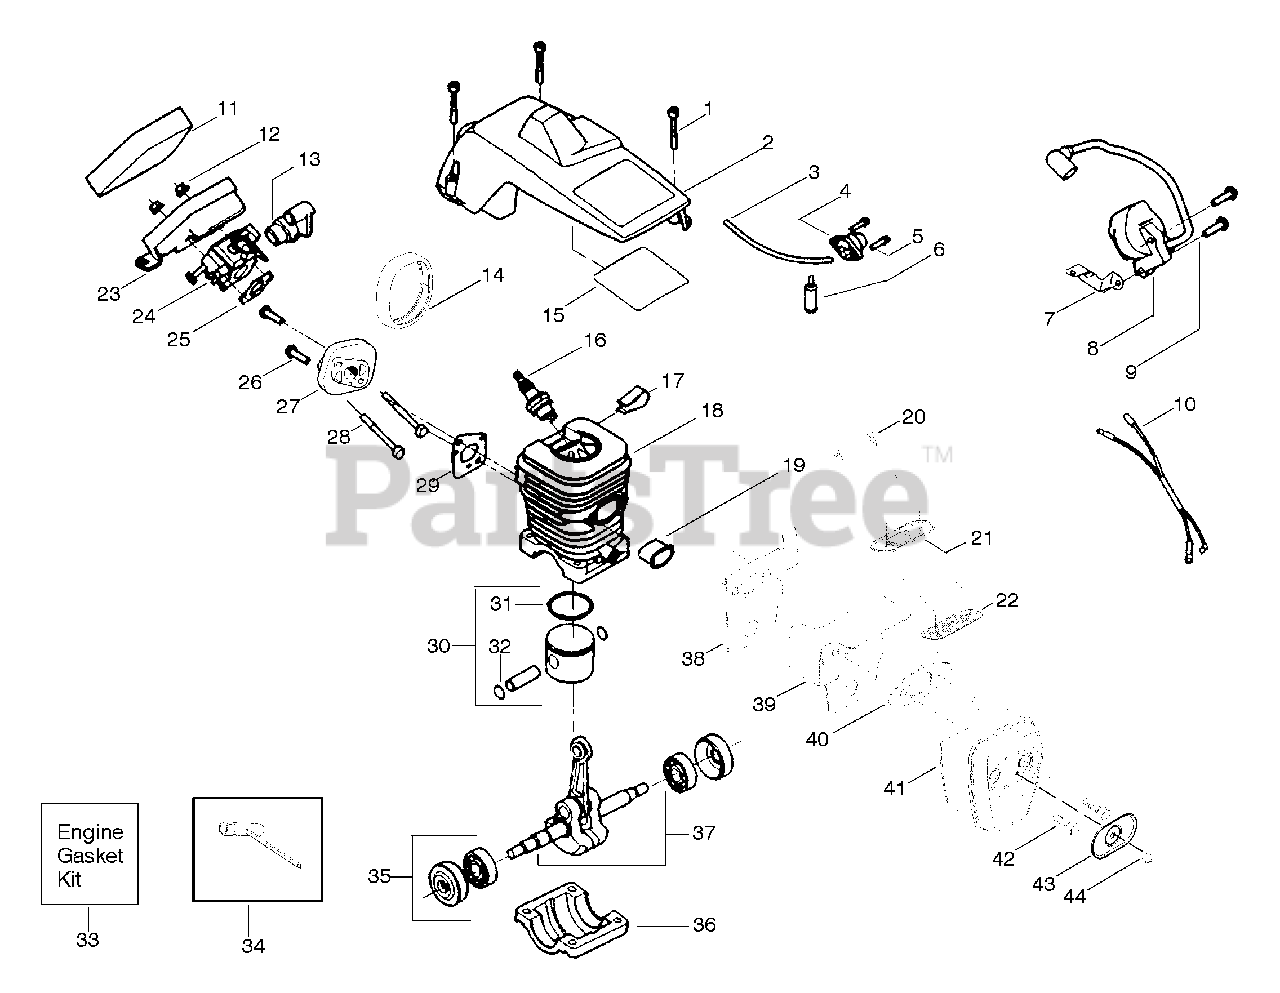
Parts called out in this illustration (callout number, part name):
2	Assy-Cylinder Shield
3	Kit-Fuel Line (Small)
4	Assy-Air Purge
6	Assy-Fuel Pick-up
7	Strap-Ground
8	Ignition Module
10	Assy-Wire Harness
11	Foam-Air Filter
13	Grommet-Carb Adjust
14	Seal-Carb Adapter
15	Reflector-Heat
16	Spark Plug (RCJ-7Y)
17	Clip-High Tension Lead
18	Kit-Cylinder
19	Insulator-Heat
20	Screw-Outlet cover
21	Cover-Outlet
22	Kit-Spark Arrestor
23	Air Filter Housing
24	Kit-Carburetor (WT-600)
24	Kit-Carburetor (WT-637)
25	Gasket-Carb.
27	Carb. Adapter
29	Gasket-Carb Adaptor
30	Kit-Piston
31	Ring-Piston
32	Retainer-Piston Pin
33	Kit-Engine Gasket
34	Bar Wrench
35	Assy-Seal & Bearing
36	Cap-Crankcase
37	Assy-Crankshaft
38	Backplate
39	Guide-Outlet
40	Gasket-Muffler
41	Assy-Muffler
42	Bolt-Muffler
43	Cover-Bolt
44	Nut-Brass
